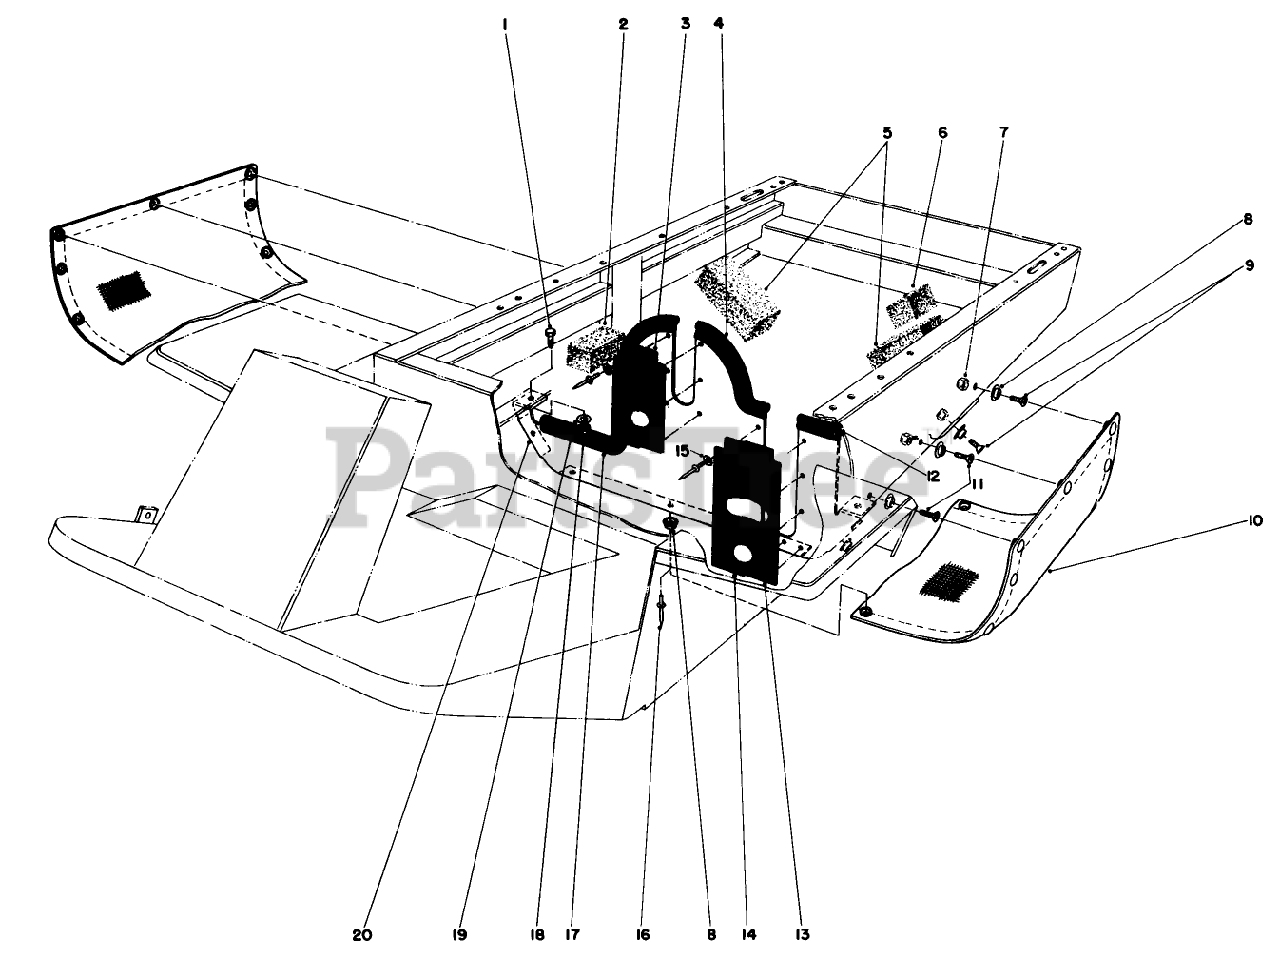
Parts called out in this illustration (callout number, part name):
1	SCREW-HH
2	SIDE FOAM
4	TRIM SEAL
5	REAR FOAM
6	LH REAR FOAM
7	NUT-HEX
8	SNAP STUD
9	6-32 X 5/8 FLAT HD SCR
10	GRASS SCREEN BAG
11	Self Tapping Screw
12	TRIM SEAL
13	LH FLAP
14	RH FLAP
15	WASHER
16	RIVET-POP
17	TRIM SEAL
18	NUT-HEX
19	WASHER-LOCK/SP
20	Shield Assembly Front (Incl. Ref. #3-4, 8, & 12-17)
